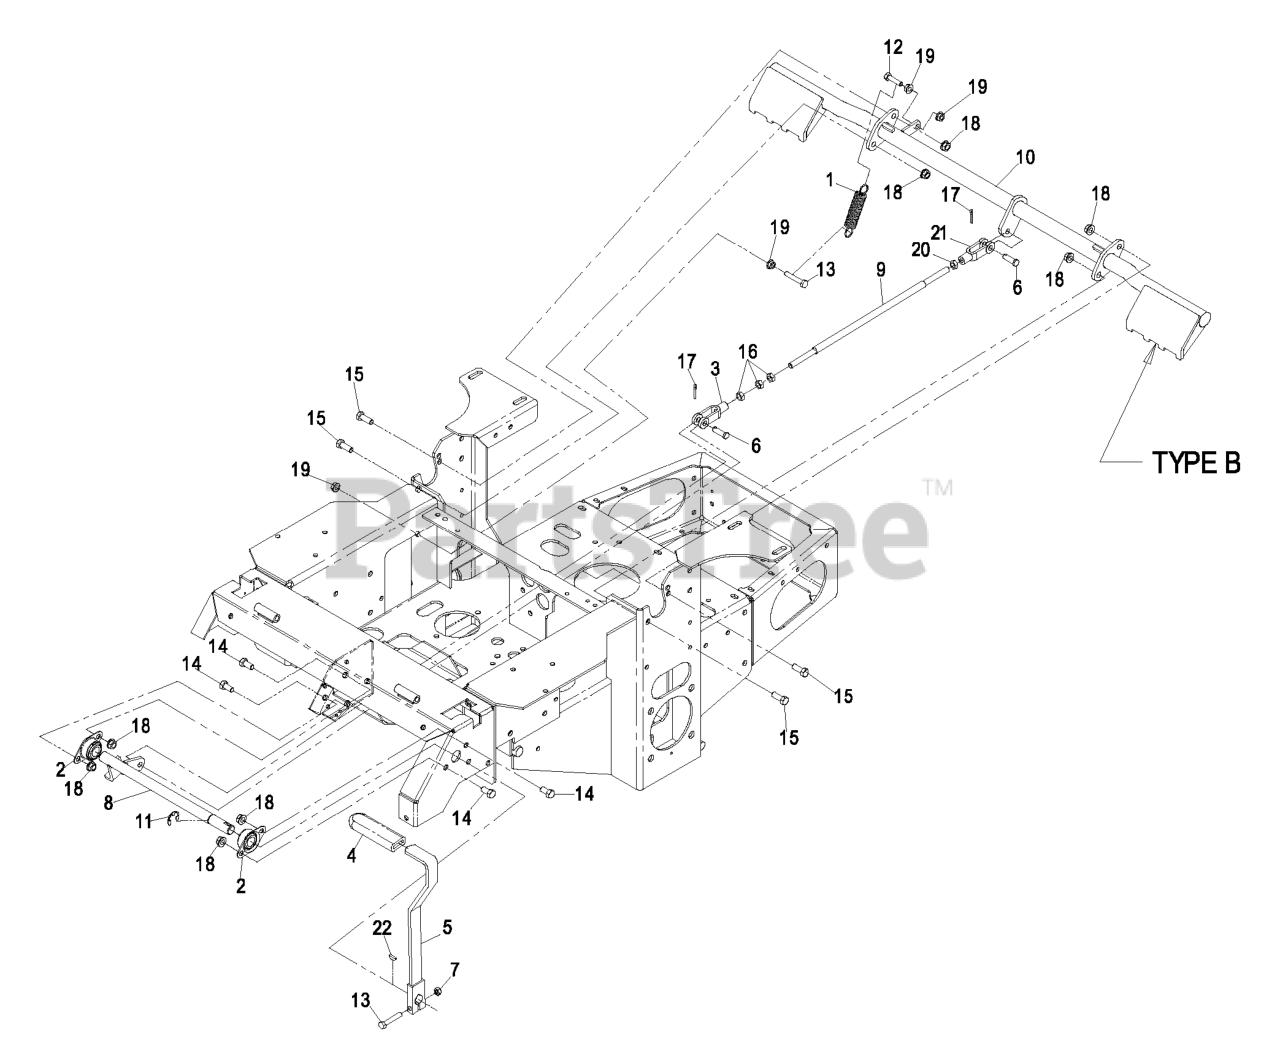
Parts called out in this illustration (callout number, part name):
1	SPRING-IDLER
2	BEARING-FLANGE, SIDE
3	YOKE-LINKAGE, BRAKE
4	GRIP-LEVER
5	HANDLE,PARK BRAKE W/GRIP
6	PIN-CLEVIS
7	NUTTORQUE ZKPLT
8	WELD,SHAFT/PARK BRAKE
9	LINKAGE, BRAKE (PLTD)
12	SCREW-HH
13	SCREW-HH
14	SCREW-HH
15	SCREW-HH
16	NUT-HEX
17	PIN-COTTER
18	NUT-HHF, WHIZ
20	NUT-HEX, LH
21	YOKE, LH YZ
22	KEY-WOODRUFF
